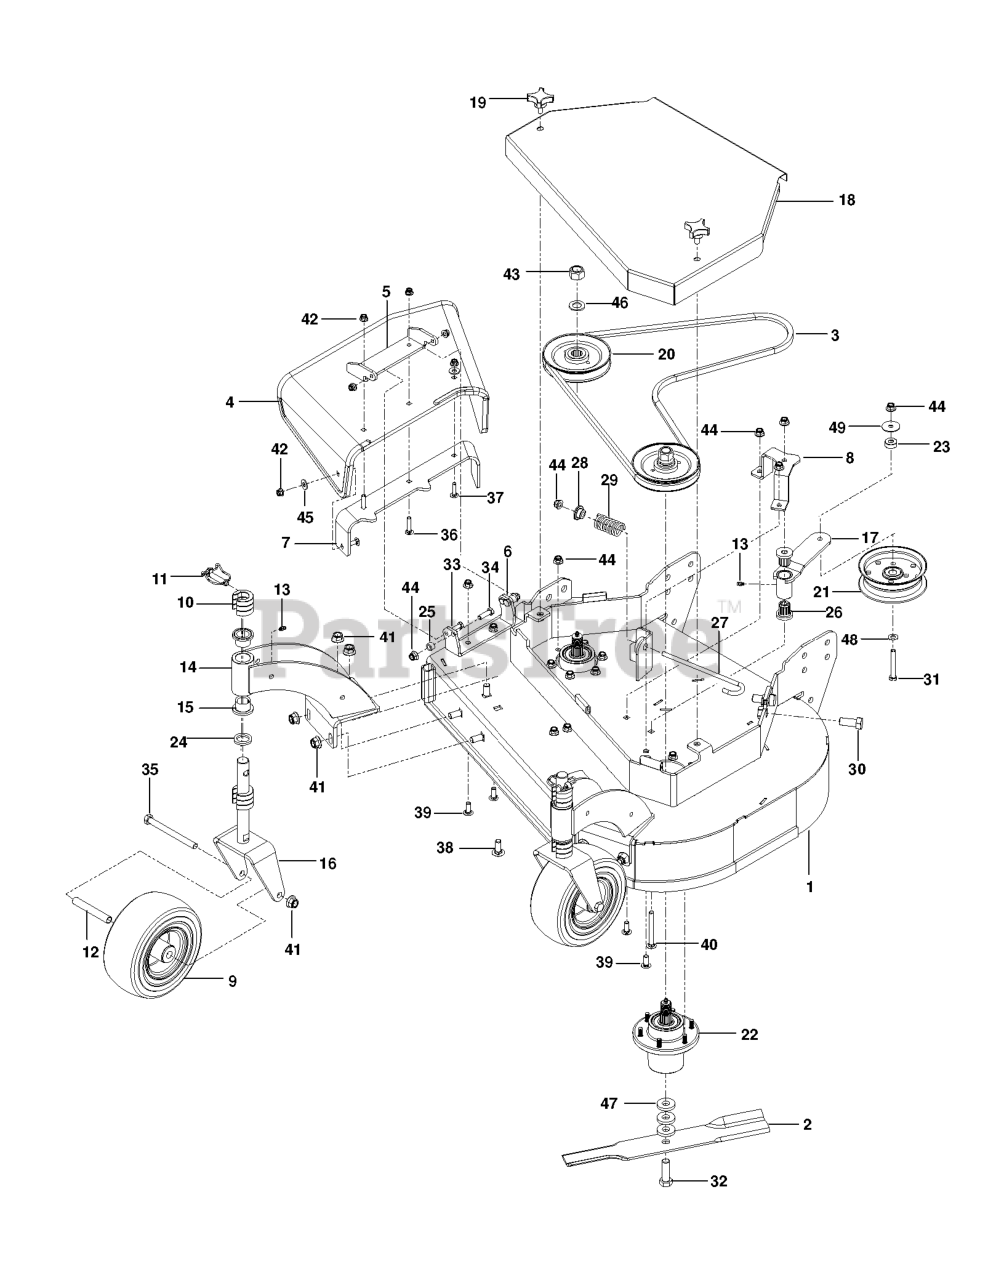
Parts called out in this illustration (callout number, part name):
1	DECK ASSY ASSY, DECK 36" GEAR
2	BLADE BLADE, 18.000 X .80 LI
3	BELT BELT, HB 80.3 EL AMD OHR
4	CHUTE CHUTE, DISCHARGE RUBBER
5	BRACKET BRACKET, DISCHARGE MOU
6	BRACKET BRACKET, DISCHARGE PIV
7	BRACKET BRACKET, DISCHARGE
8	BRACKET BRACKET, IDLER
9	WHEEL ASSY ASSY, WHEEL & TIRE
10	SPACER C-SPACER, 1.00 X 1.77 X
11	PIN PIN, LNC .438 X 2.00
12	TUBE TUBE, CASTER AXLE
13	FITTING FITTING, 1/4-28 STRGT
14	STRUT STRUT FRONT FXWLK HUSQ
15	BEARING BRG, FLG 1.00 X 1.25 X
16	YOKE CASTER YOKE HUSQ
17	OFFSET PULLEY IDLER ARM WITH O
18	SHIELD SHIELD 36 GRWLK HUSQ
19	KNOB KNOB, 3/8 -16 X .75
20	PULLEY PULLEY, SPINDLE 5.75 OD
21	PULLEY PULLEY, FLAT 5.00 X .37
22	SPINDLE ASSY, SPINDLE HOUSING
23	BUSHING BUSHING, .380 X 1.00 X
24	BUSHING BUSHING, 1.03 X 1.50 X
25	BUSHING BUSHING, SLV
26	BEARING BRG, FLG M10 X M25 X M
27	BOLT J-BOLT, 3/8-16 X 7.88
28	KEEPER KEEPER, SPRING
29	SPRING SPRING, COM 1.22 X .162
30	BOLT BOLT, HEX 5/8-11 1.5" GR8
31	BOLT BOLT HEX .38-16 X 2.75 GR
32	BOLT BOLT HEX .62-11 X 2.00 G
33	BOLT BOLT HEX .31-18 X 1.00 GR
34	BOLT BOLT HEX .38-16 X 1.25 GR
35	BOLT BOLT HEX .50-13 X 5.50 G
36	BOLT BOLT RDHDSQNK .31-18 X 1.
37	BOLT BOLT RDHDSQNK .31-18 X 1.
38	BOLT BOLT RDHDSQNK .50-13 X 1.
39	BOLT BOLT RDHDSHSQNK .38-16 X
40	BOLT RDHDSQNK .38-16 X 3.
41	NUT NUT, LK-NYL-FLG .50-13 YWZ
43	LOCK NUT LOCKNUT, 3/4-16 CROWN
45	WASHER WASHER, FL-STL .38 X .8
46	WASHER WASHER, .75 X 1.3125 X
47	WASHER WASHER, FL-STL .630 X 1
49	WASHER WASHER, FL-STL .38 X 1.
